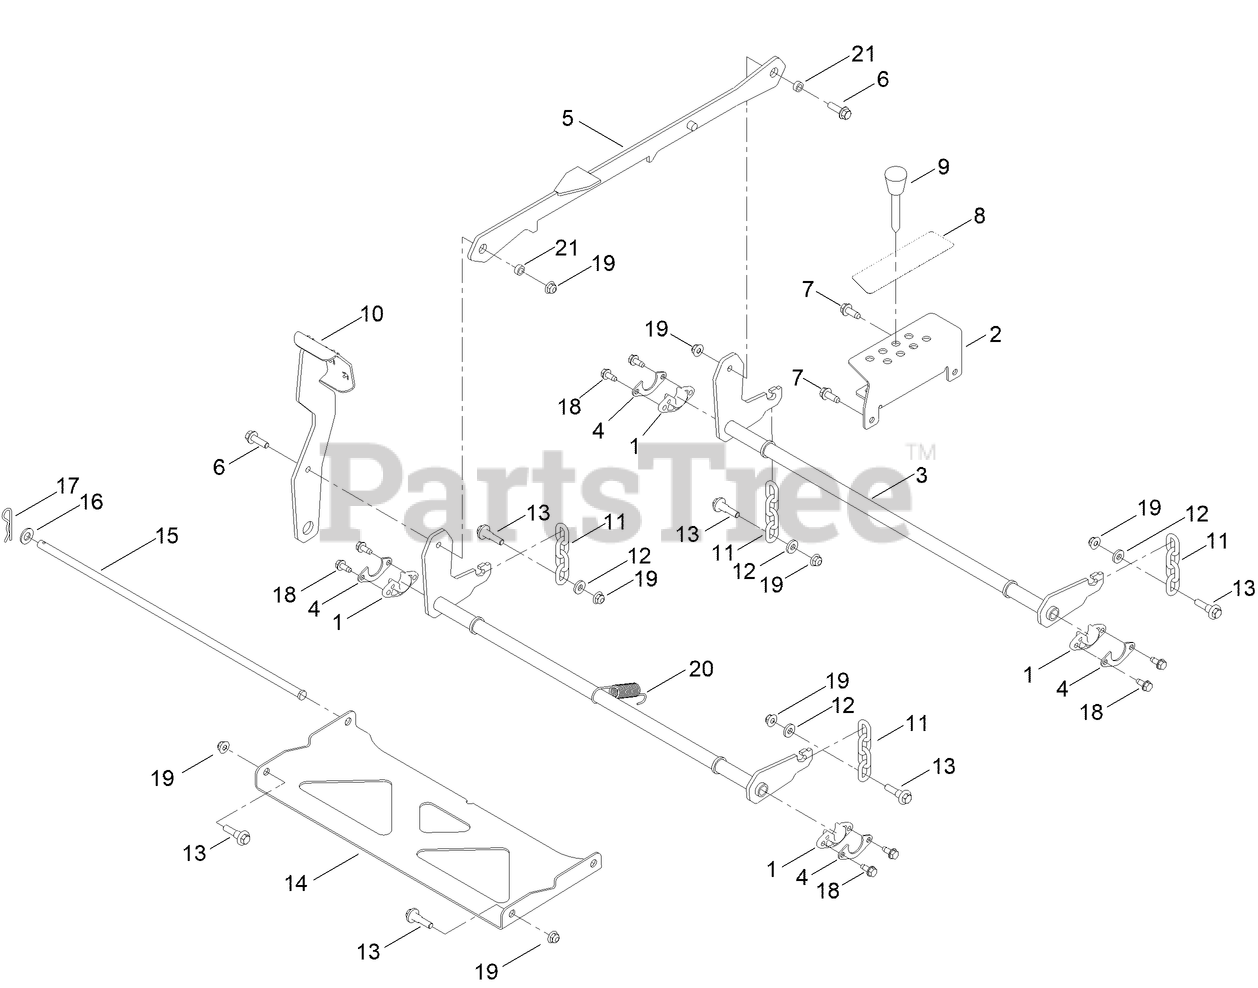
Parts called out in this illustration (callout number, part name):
1	BEARING-FLANGE
2	BRACKET-HOC
3	PIVOT ASM-DECKLIFT [BLK-TXT]
4	GUSSET-DECK LIFT
5	LINK ASM-HOC [BLK-TXT]
6	SCREW-HHF
7	SCREW-HWH
8	DECAL-HOC, TC
9	HOC PIN ASM
10	PEDAL ASM [BLK-TXT]
11	CHAIN-DECKLIFT, 4-LINK
12	SPACER-HUB, BLOWER
13	BOLT-SHOULDER
14	PAN-DECK PIVOT
15	PIN-DECK
16	WASHER-FLAT
17	PIN-HAIR
18	SCREW-HWHTF
19	NUT-HF, NI
20	SPRING-EXTENSION
21	SPACER
